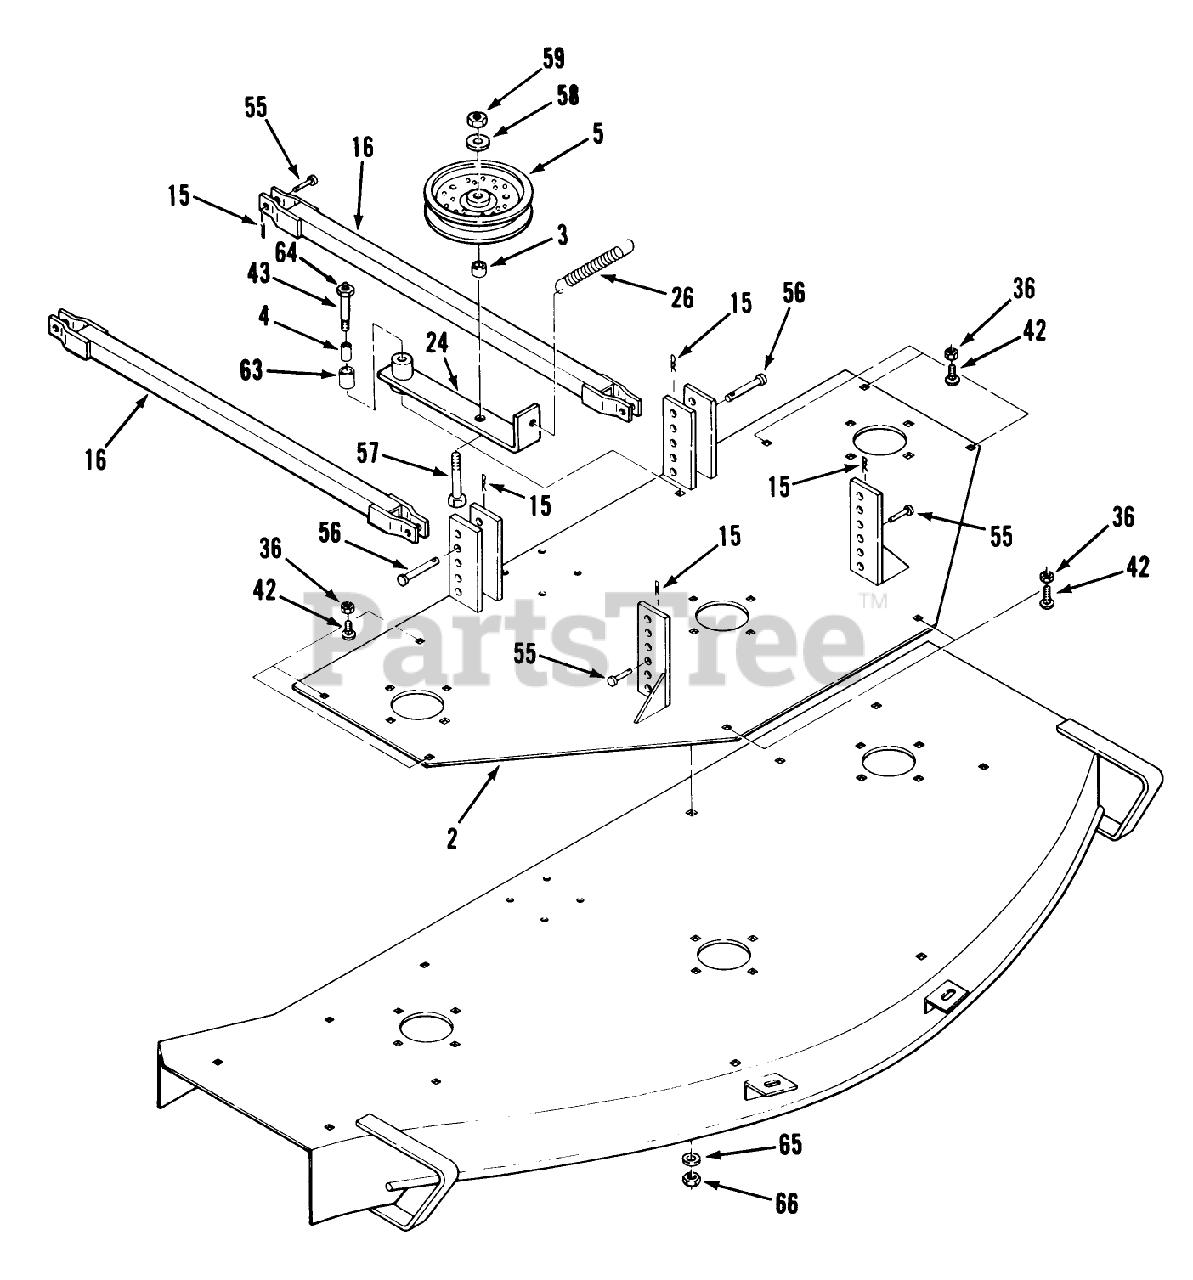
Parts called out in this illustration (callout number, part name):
2	50" MWR DECK PLATE R
3	SPACER
4	BUSHING
5	PULLEY FLAT B
15	HAIRPIN
16	Bar-Stabilizer
24	ASS'Y-IDLER ARM R
26	SPRING-EXTENSION
36	Nut
42	Bolt
43	BOLT-SHOULDER
55	Clevis Pin 3/8 x 1 1/4
56	Clevis Pin 3/8 x 2-1/4
57	Bolt 1/2-13 X 2
58	Washer
59	Nut
63	BUSHING
64	Zerk
65	Washer
66	E.S. Nut 3/8-16
